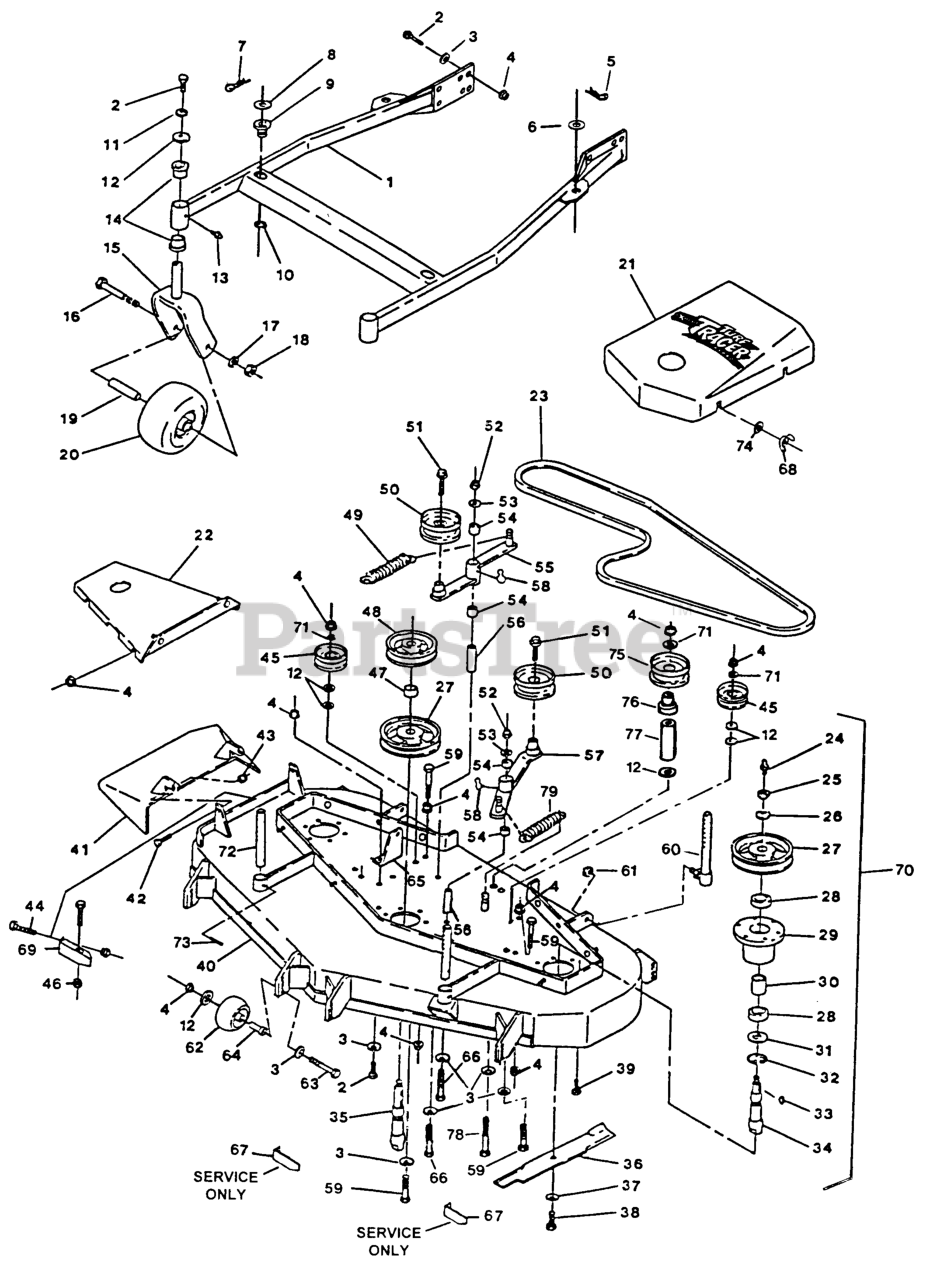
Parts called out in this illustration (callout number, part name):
5	PIN,HAIR COTTER
8	WASHER-FLAT
9	BUSHING-DECK
12	WASHER
14	BEARING-FLANGED
19	SPACER
23	BELT,BLADE DRIVE
26	WASHER-SPRING
27	SHEAVE,BLADE DRIVE
30	SPACER,BEARING
31	SEAL,MECHANICAL DUST
32	RING,SNAP WLDS N5000-244
34	SPINDLE-OUTER BLADE
35	SPINDLE-CENTER BLADE
37	WASHER-SPRING
39	SCRW,TPTTE HH
41	WLD,CHUTE DISCHARGE
45	IDLER,PULLEY
47	SPACER-TUBE
48	SHEAVE,MOWER DRIVE
49	SPRING-EXTENSION
50	IDLER,PULLEY
54	SLEEVE-BEARING
55	ASM,IDLER ARM
56	BUSHING-PIVOT, IDLER
57	ASM,IDLER ARM
62	ROLLER-SCALP, ANTI
64	BUSHING-ROLLER
65	BRACKET,SPRING ANCHOR
66	SCREW-HH
68	NUT-WING
69	WLD,BAFFLE DISCHARGE
72	ROD,DECK SUPPORT
75	PULLEY-IDLER
76	BUSHING,IDLER
77	SPACER-FENDER
79	SPRING-EXTENSION
